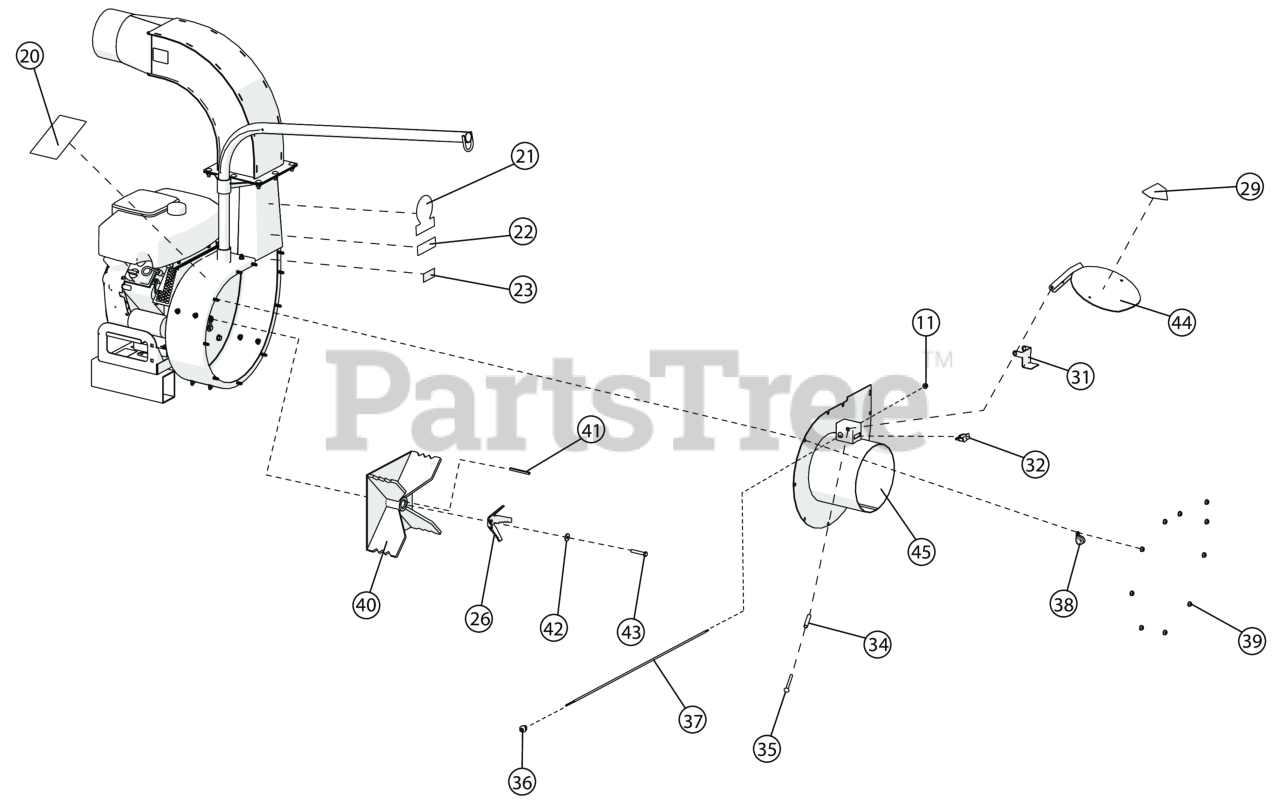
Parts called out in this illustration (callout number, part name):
11	NUT-HEX-NYLK, FLG .3125-18 ZP
20	LABEL QL INSTRUCTION/WARN
21	LABEL LOGO DL12/13/18
22	LABEL DL PIRANHA
23	LABEL, WARNING LINER DL
26	DEBRIS REDUCER DL12/13/18
29	LABEL WARNING OPEI
31	LEVER HOSE SWITCH
32	SWITCH, SAFETY INTERLOCK
34	SPACER 3/8" X 2 1/2"
35	BOLT CARRIAGE 5/16"-18 X 3 1/2" ZP
36	STRAIN RELIEF
37	HARNESS WIRE DL 12/13/18 KILL SWITCH
38	CLAMP ROUTING FUEL LINE
39	NUT FLANGE 5/16"-18 ZP
40	SEE: 810930
41	KEY 1/4" SQ X 3 1/4"
42	WSHR-STL, BLV, .386" X 1.063" X .082" MZ
43	SCREWCAP 3/8" X 2 1/4" GR 8 ZP
44	FLAPPER WA 10"
45	PLATE FRONT WA DL18
